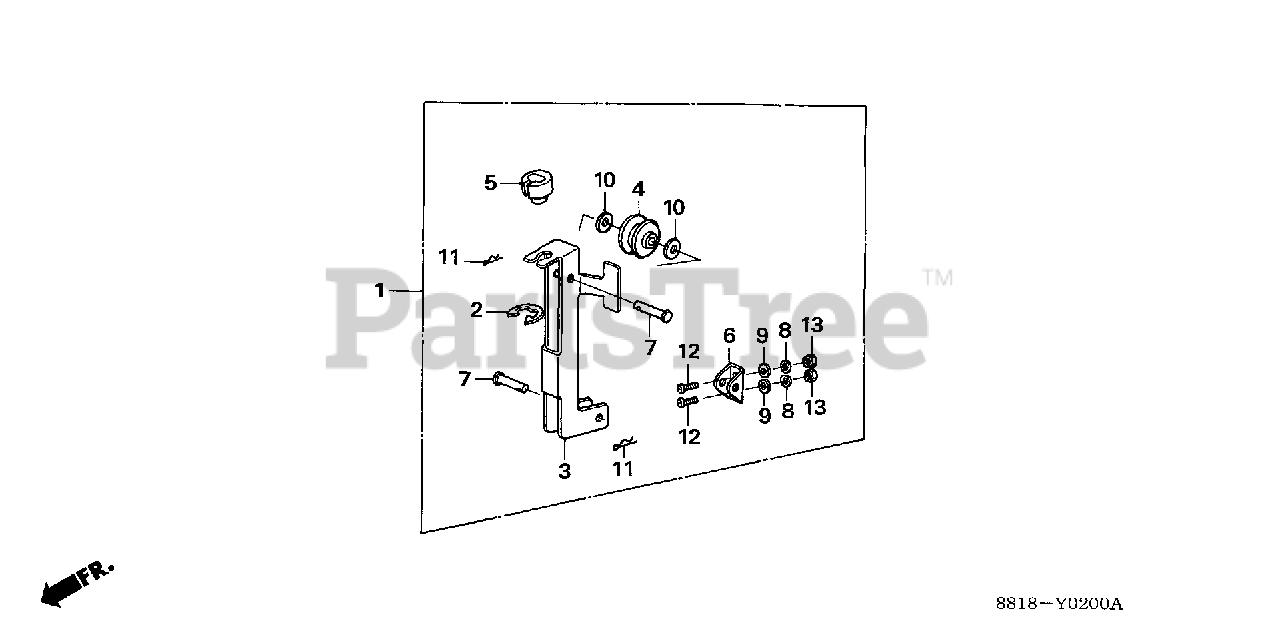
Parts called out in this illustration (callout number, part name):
1	STARTER KIT, VERTICAL (N/A: SEE COMPONENTS)
2	E-RING
3	STAY, VERTICAL STARTER
4	IDLER, VERTICAL STARTER
5	GUIDE, ROPE
6	BRACKET, VERTICAL STARTER
7	PIN, VERTICAL STARTER
8	WASHER, SPRING (6MM)
9	WASHER, PLAIN (6MM)
10	WASHER (10MM)
11	PIN, LOCK (10MM)
12	SCREW, PAN (6X12)
13	NUT, HEX. (6MM)
